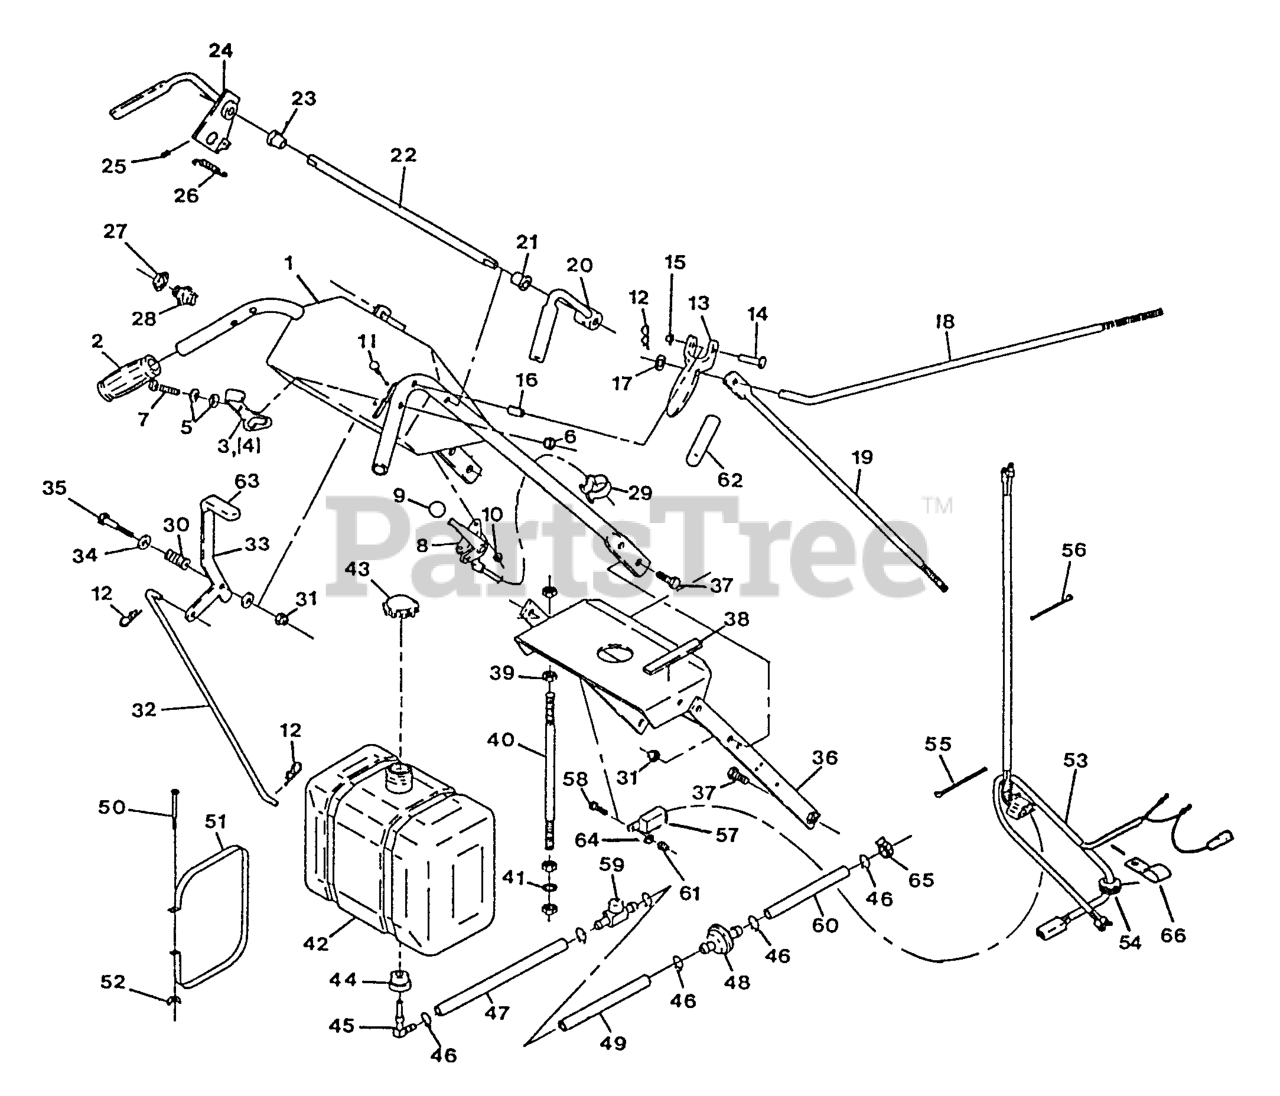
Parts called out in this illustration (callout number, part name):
3	LATCH,W/GRIP RH
4	LATCH,W/GRIP LH
5	WASHER-SPRING
8	CABLE,THROTTLE CONTROL
9	KNOB-BALL
11	BOLT-CARR
12	PIN-COTTER
13	DRIVE LEVER ASM
14	PIN-LEVER, DRIVE
15	NUT-PUSH
16	PIN-ROLL
18	LINKAGE,BRAKE
19	LINKAGE,CALIPER
21	BUSHING-NYLON
22	ROD,CONNECTING
23	BUSHING,FLANGED
25	SCREW-SET
26	SPRING-EXTENSION
28	SWITCH,OPERATOR CNTRL
29	CLIP-CABLE
30	SPRING-COMPRESSION
32	LINKAGE-BLADE, UPPER
38	PAD,PLASTIC TANK
43	CAP-FUEL
45	ELBOW-TANK, FUEL
47	FUEL LINE
50	SCRW,MACH CRPH
52	WINGNUT
53	HARNESS,WIRING KAW
54	GROMMET
55	TIE-PLASTIC
56	TIE-CABLE
57	MODULE-INTERLOCK
59	VALVE-FUEL
62	GRIP-LEVER, DRIVE
63	GRIP-LEVER
65	CLAMP-HOSE
